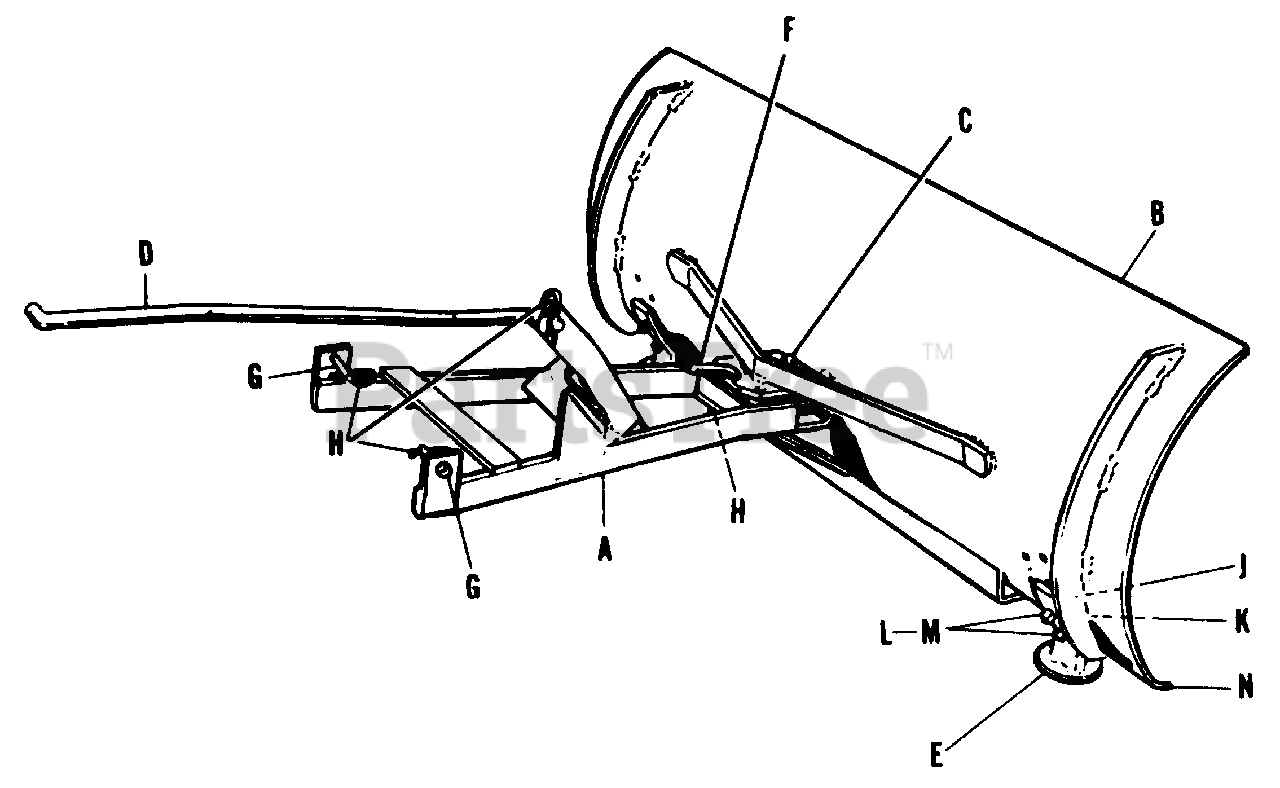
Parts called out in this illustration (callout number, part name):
A	Push Bar Assembly
B	Blade Assembly
C	Pin, King, 1/2" dia. x 2 1/2"
D	Rod, Front Lift
E	Shoe Assembly
G	Pin
H	Clip, Spring
J	Bolt, Carriage, 3/8"-16 x 3/4"
K	Bolt, Carriage, 3/8"-16 x 3/4"
L	Washer, Lock, 3/8"
M	Nut, Hex. Full, 3/8"-16 N.C.
N	Plate, Wear
